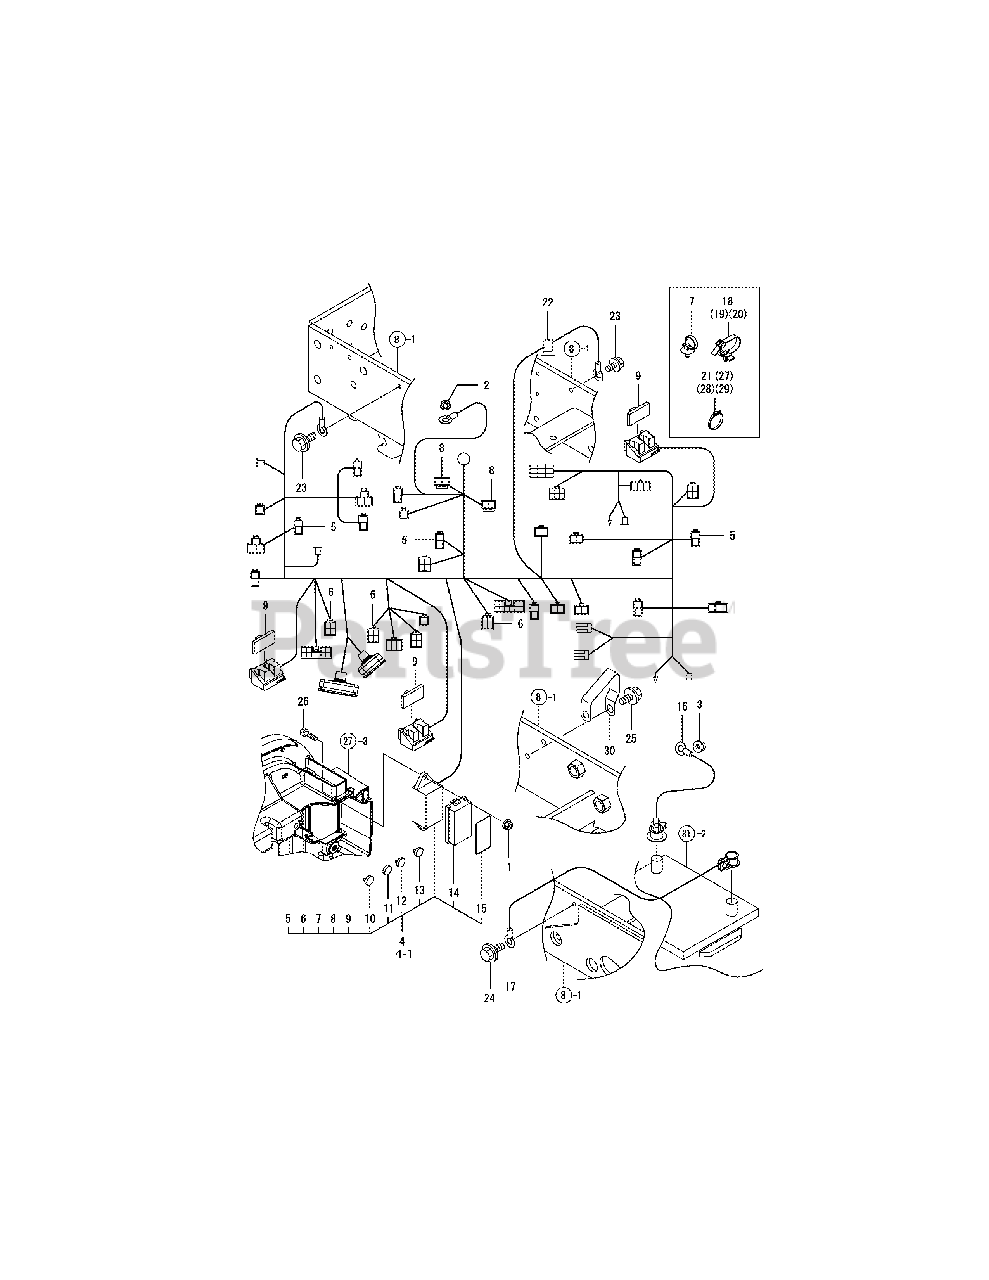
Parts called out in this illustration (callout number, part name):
1	NUT W/WASHER 6
2	NUT W/WASHER 6
3	NUT W/WASHER 8
4	HARNESS ASSY,WIRE
4-1	HARNESS ASSY,WIRE
8	BLOW, SLOW FUSE 60A
14	COVER, FUSE BOX
16	CABLE, BATTERY
17	CABLE,BATTERY NEG.
22	STICKER 18,WIRE
23	BOLT M 8X 16 PLATED
24	BOLT M 8X 16 PLATED
25	BOLT M10X 20 PLATED
